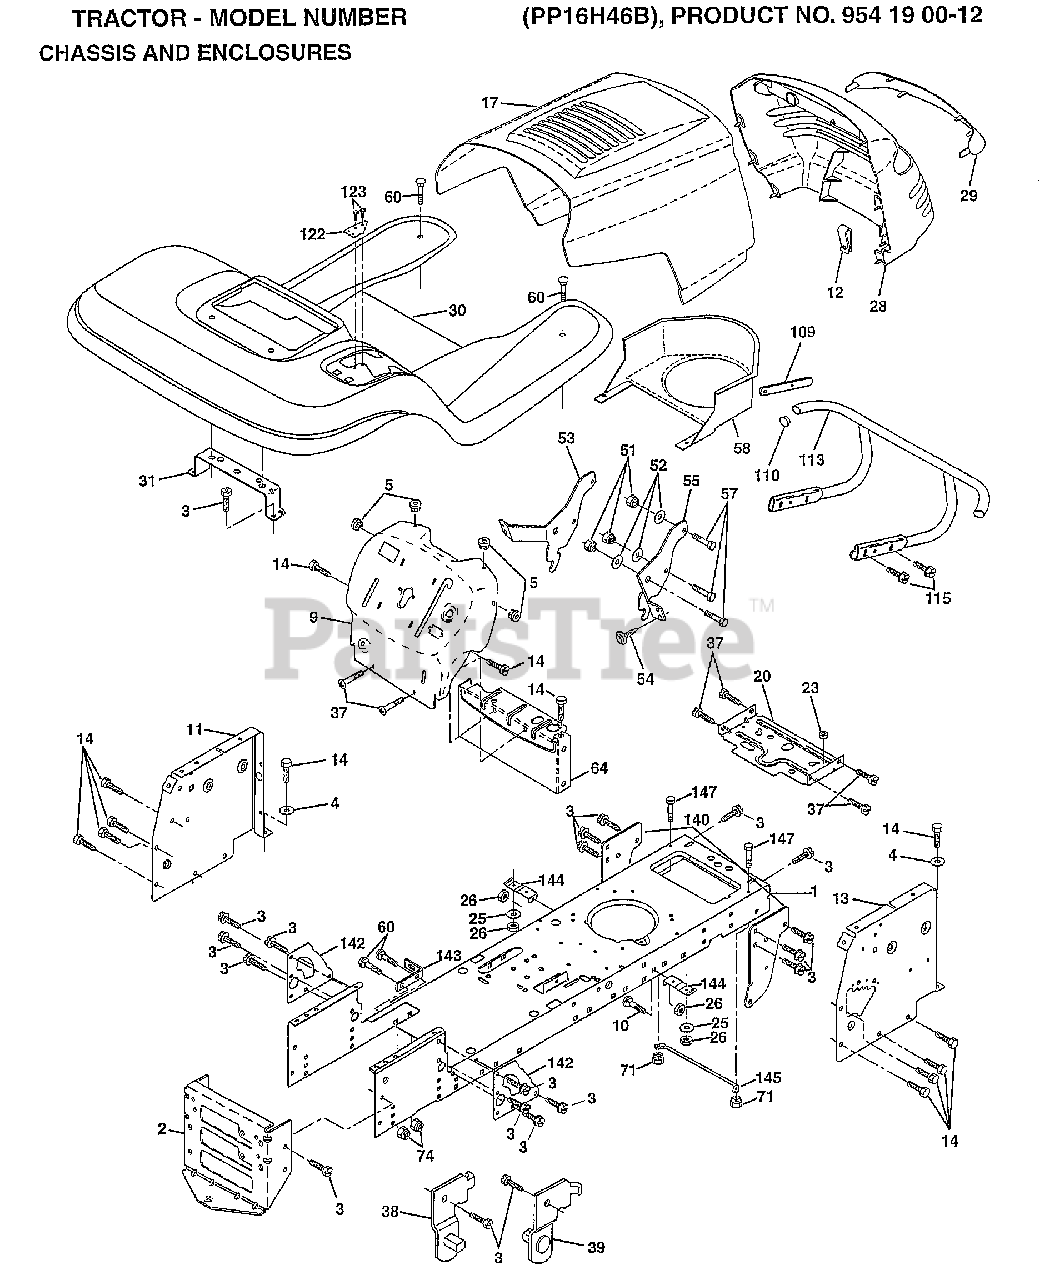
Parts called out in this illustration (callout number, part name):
1	CHASSIS
3	SCREW
4	WASHER
5	BUMPER-HOOD/DASH
11	"PANEL-DASH,LH"
12	CLIP.TINNERMAN
13	"PANEL-DASH,RH"
14	SCREW LT
20	"PLATE-MTG,BATT/FU"
25	WASHER
26	NUT
28	GRILLE-MS428
29	LENS GRILLE
30	FENDER/FOOTREST
31	BRACKET SUPT FEND
37	SCREW LT
38	BRACKET ASM LH
39	BRACKET ASM RH
51	NUT
52	WASHER
53	BRACKET.GRILLE.LH
55	BRACKET.GRILLE.RH
58	AIR DUCT
60	BOLT
64	DASH-LOWER
109	BRACKET.EXT.BUMP.
110	PLUG.PLASTIC
113	BUMPER.ASM
115	SCREW
122	"BRKT SHIFT,LT"
123	"SCREW-TT,10-32 FL"
140	BRKT SUSPENSION
142	PLATE.REINFORCEMT
143	"BRKT-S'BAR,CHASSI"
144	BRKT-FOOTREST
145	"ROD POVOT,CHASSIS"
147	BOLT LT
